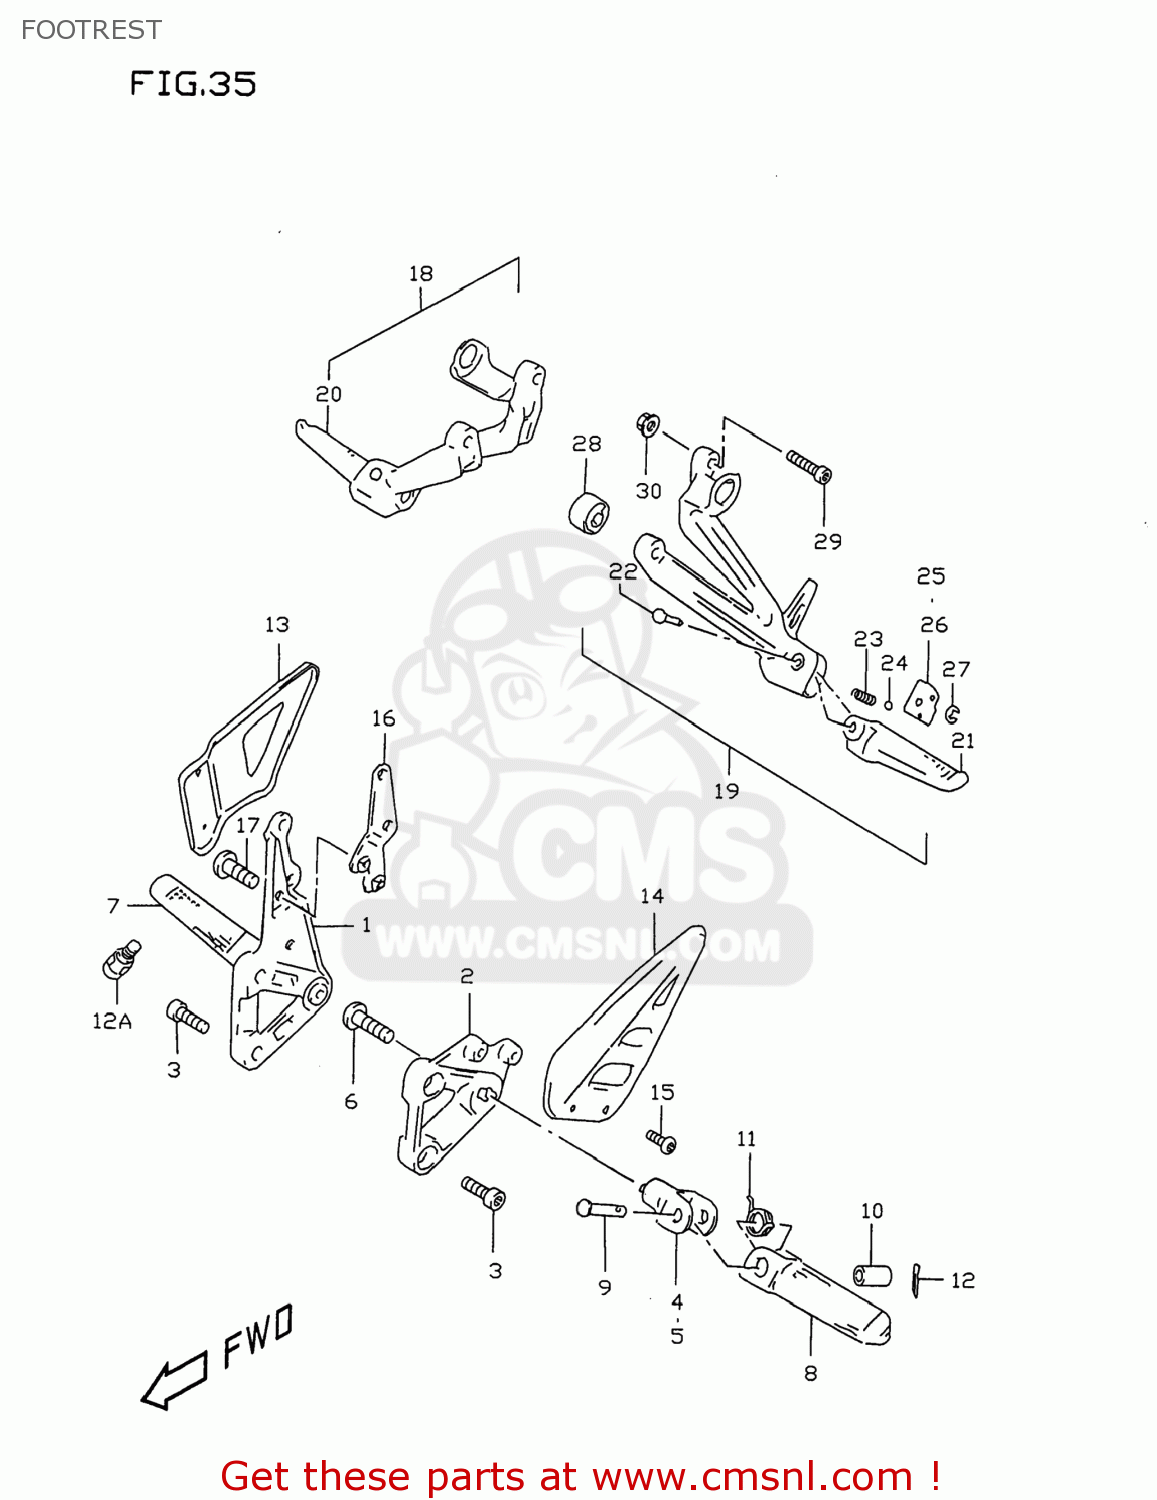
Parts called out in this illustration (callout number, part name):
1	BRACKET,FR FOOTREST,R
2	BRACKET,FR FOOTREST,L
3	BOLT
4	HOLDER,FOOTREST,R
5	HOLDER,FOOTREST,L
6	BOLT(10X28)
7	BAR,FOOTREST,R
8	BAR,FOOTREST,L
9	PIN
10	SPACER(8.1X12X22)
11	SPRING
12	PIN 20X15
12A	BOLT,BANK SENSOR
13	GUARD,FR FOOTREST,R
14	GUARD,FR FOOTREST,L
15	SCREW(5X10)
16	REINF,FOOTREST BRACKET,R
17	SCREW(6X16)
18	FOOTREST ASSY,PILLION,R
19	FOOTREST ASSY,PILLION,L
20	BAR,PILLION FOOTREST,RIGHT
21	BAR,PILLION FOOTREST,LEFT
22	PIN
23	SPRING
24	BALL
25	PLATE,PILLION,RIGHT
26	PLATE,PILLION,LEFT
27	E-RING
28	BUSH
29	BOLT
30	NUT
